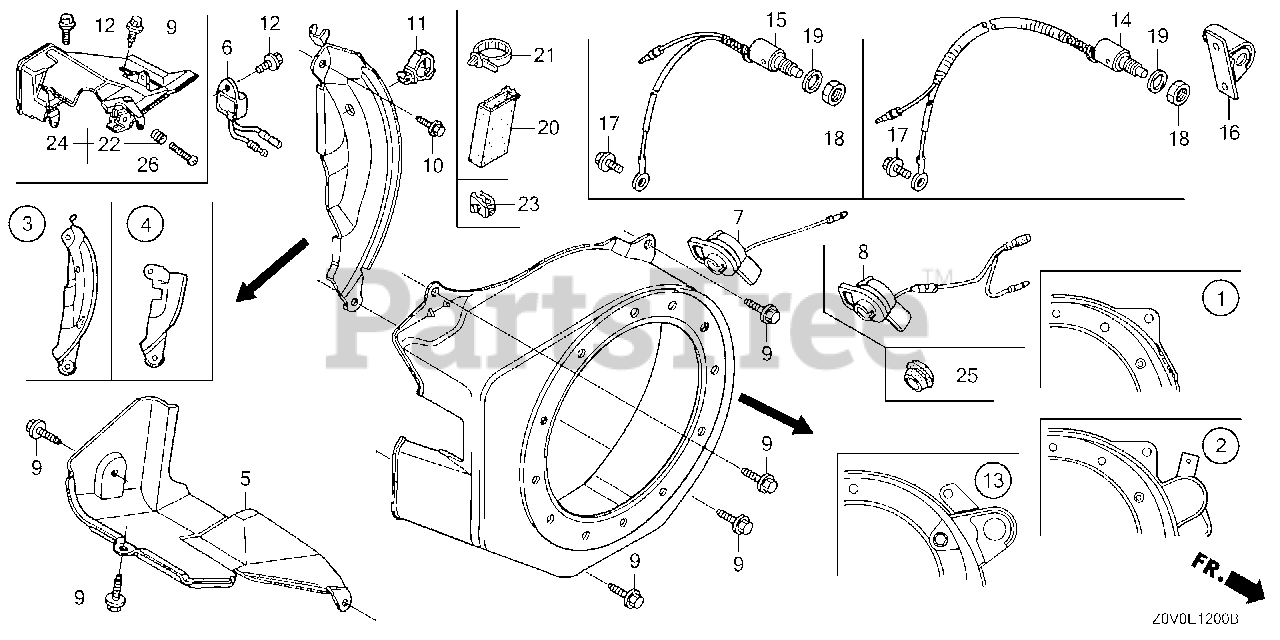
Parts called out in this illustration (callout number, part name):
1	COVER, FAN *NH1* (BLACK)
3	PLATE, SIDE (OIL ALERT)
6	ALERT UNIT, OIL
8	SWITCH ASSY., ENGINE STOP (TOYO DENSO)
8	SWITCH ASSY., ENGINE STOP
9	BOLT, FLANGE (6X12) (CT200)
10	BOLT, FLANGE (6X20) (CT200)
11	CLIP, HARNESS
12	BOLT, FLANGE (6X8)
